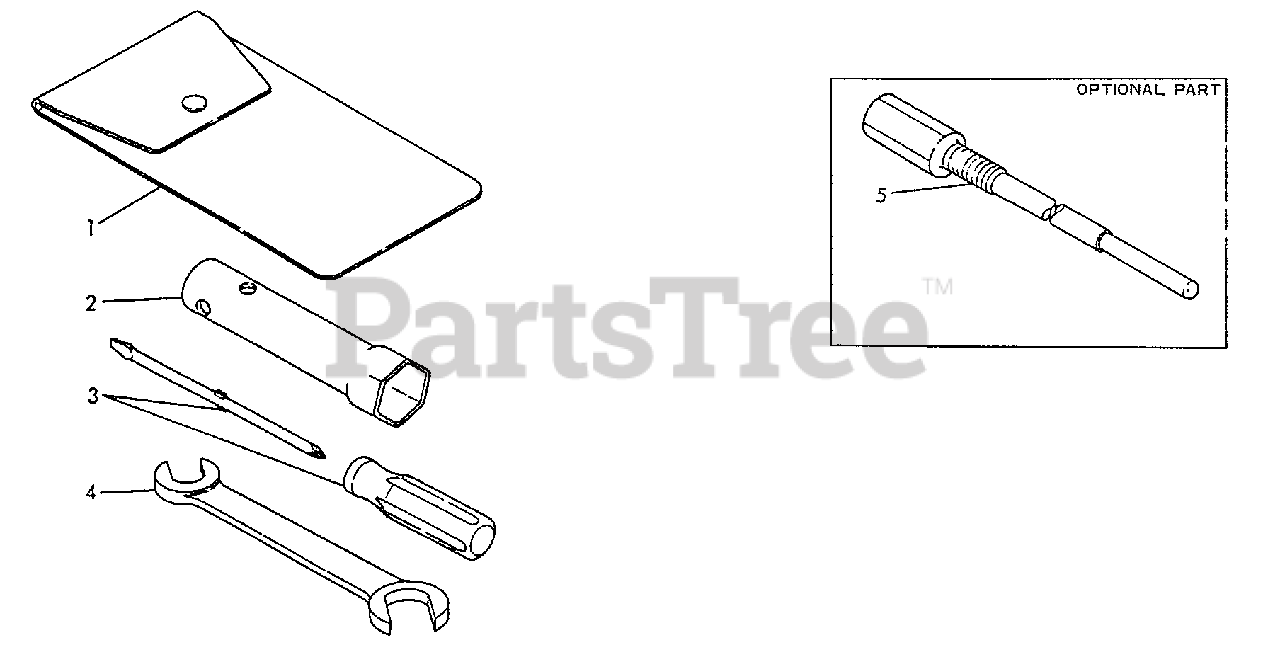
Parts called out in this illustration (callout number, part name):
1	BAG, TOOL
2	BOX SPANNER - 21
3	SCREWDRIVER
4	WRENCH 10×12
5	REMOVER, ROTOR
